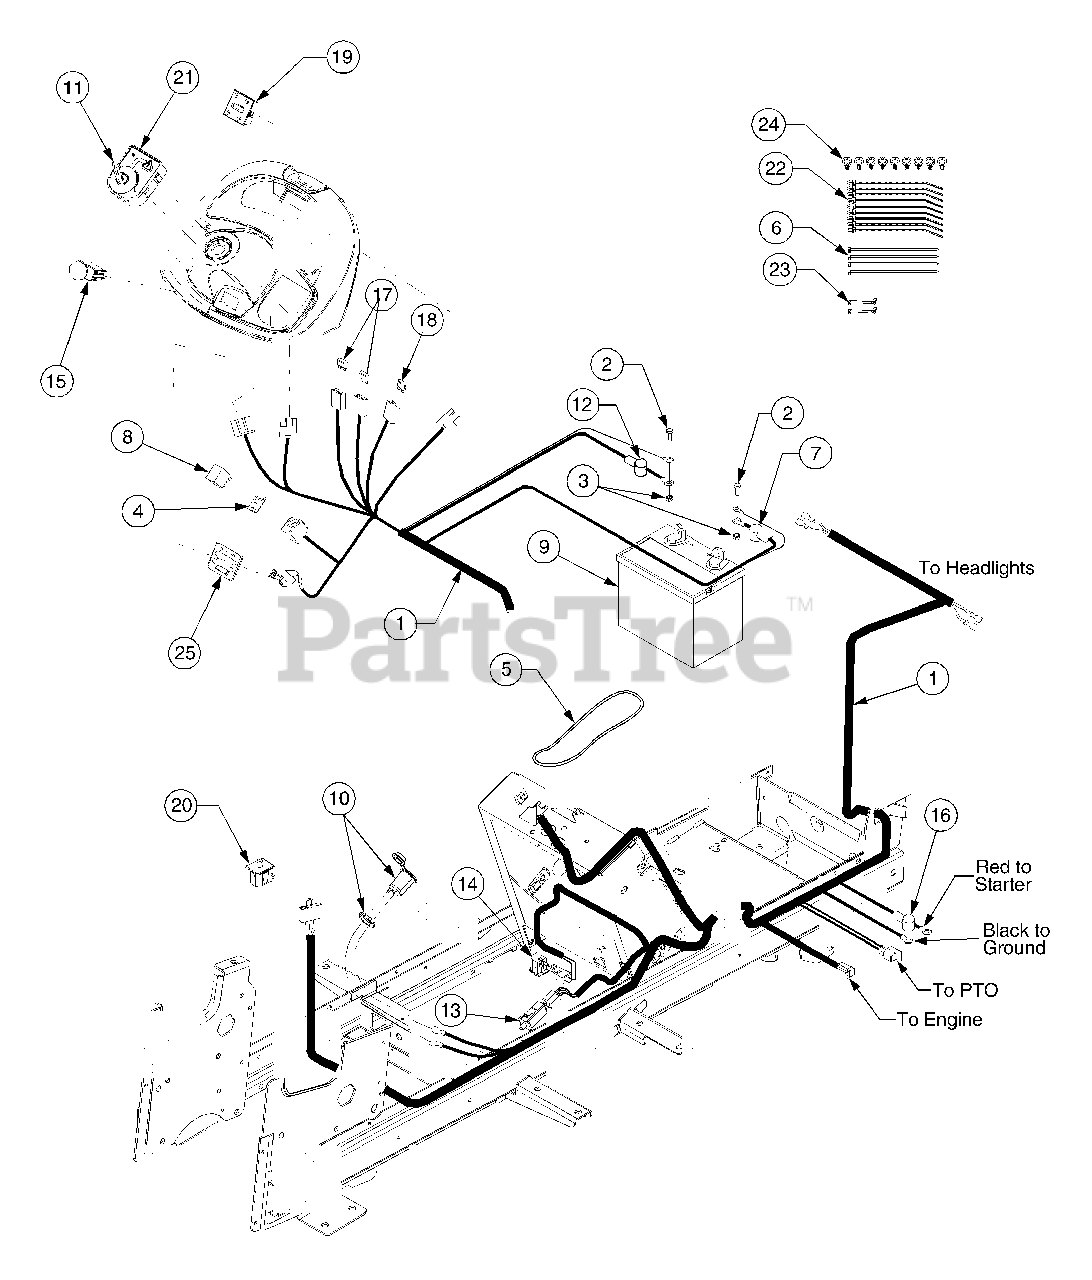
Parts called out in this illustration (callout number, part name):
1	Wire Harness, Main
2	Screw, Hex, 1/4-20 x .75 GR5
4	Gasket, Silicone
5	Strap, Battery Retainer
6	Tie, Self-Clinch Cable
7	Cover, Terminal Black
8	Relay
10	Receptacle, Power 12V
11	Key, Ignition
12	Cover, Terminal Red
13	Switch, Interlock (Brake)
14	Switch, Snap Mount (Reverse)
15	Switch, PTO
16	Cover, Terminal Red
17	Fuse, 25 Amp
18	Fuse, 5 Amp
19	Meter, Indicator / Hour
20	Switch, Snap Mount (Seat)
21	Switch, Key/Module
22	Tie, Pushmount
23	Clip, Wire
24	Clip, Cable
25	Bracket, PTO Switch Retainer
